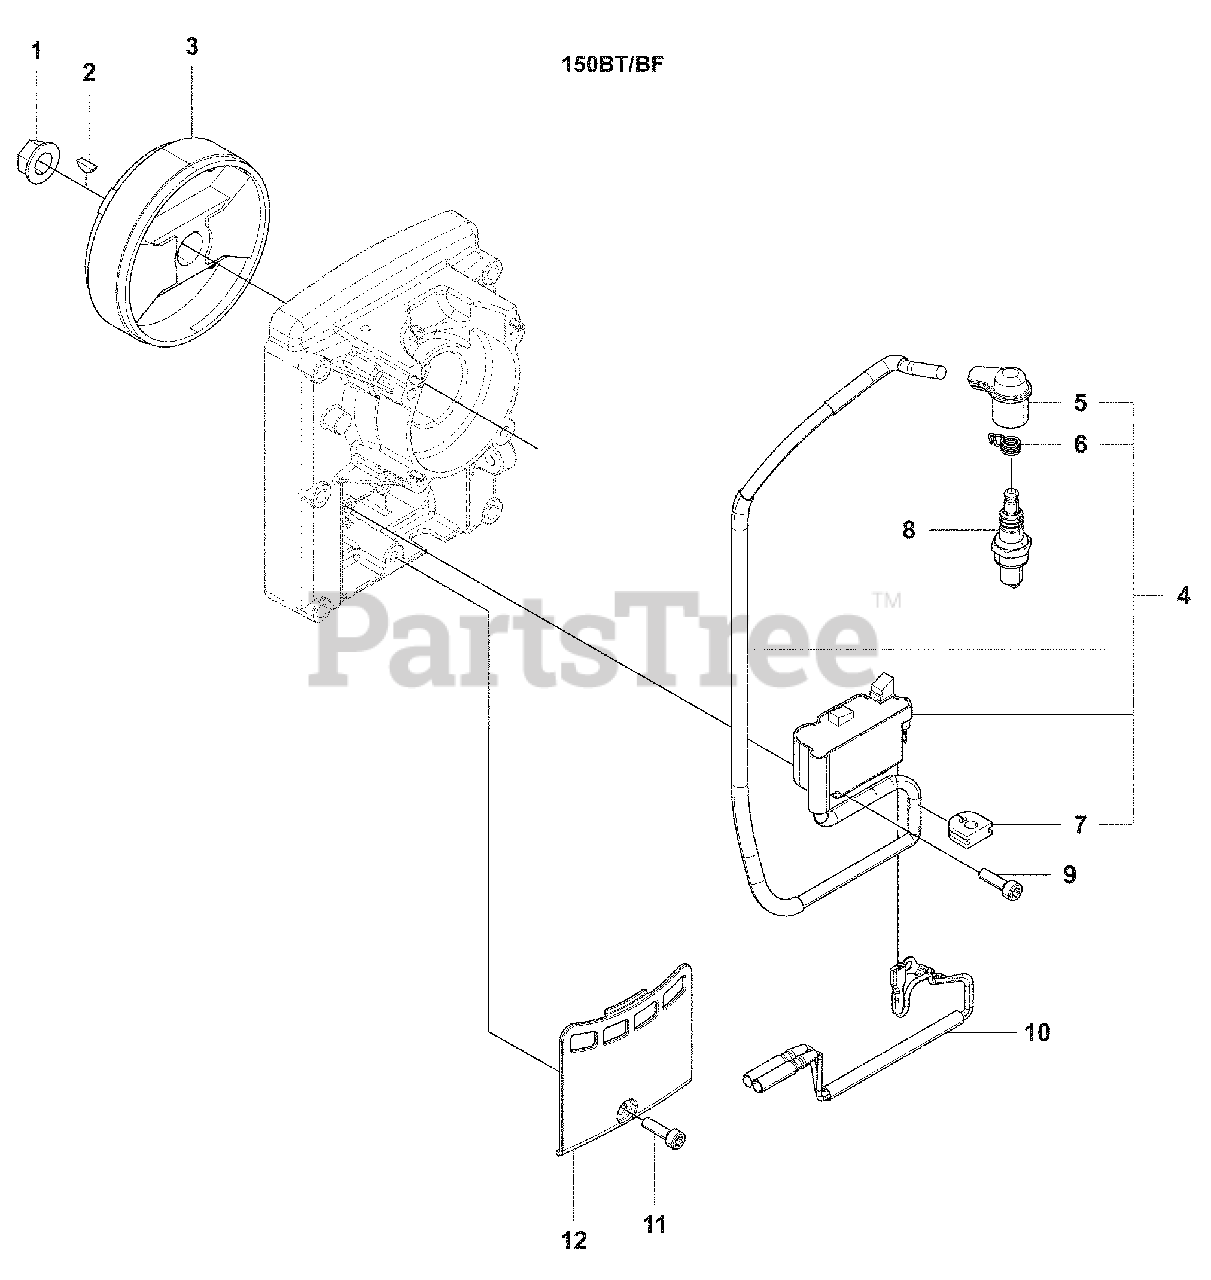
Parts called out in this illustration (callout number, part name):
1	Nut
2	Flywheel Key
3	Rotor
4	Ignition Coil
5	Cap
6	Spring
8	Spark Plug, CMR7H BLYB
9	Torx Bolt, M4 X L16
10	Cord, Complete
11	Torx Bolt, M4 X L16
